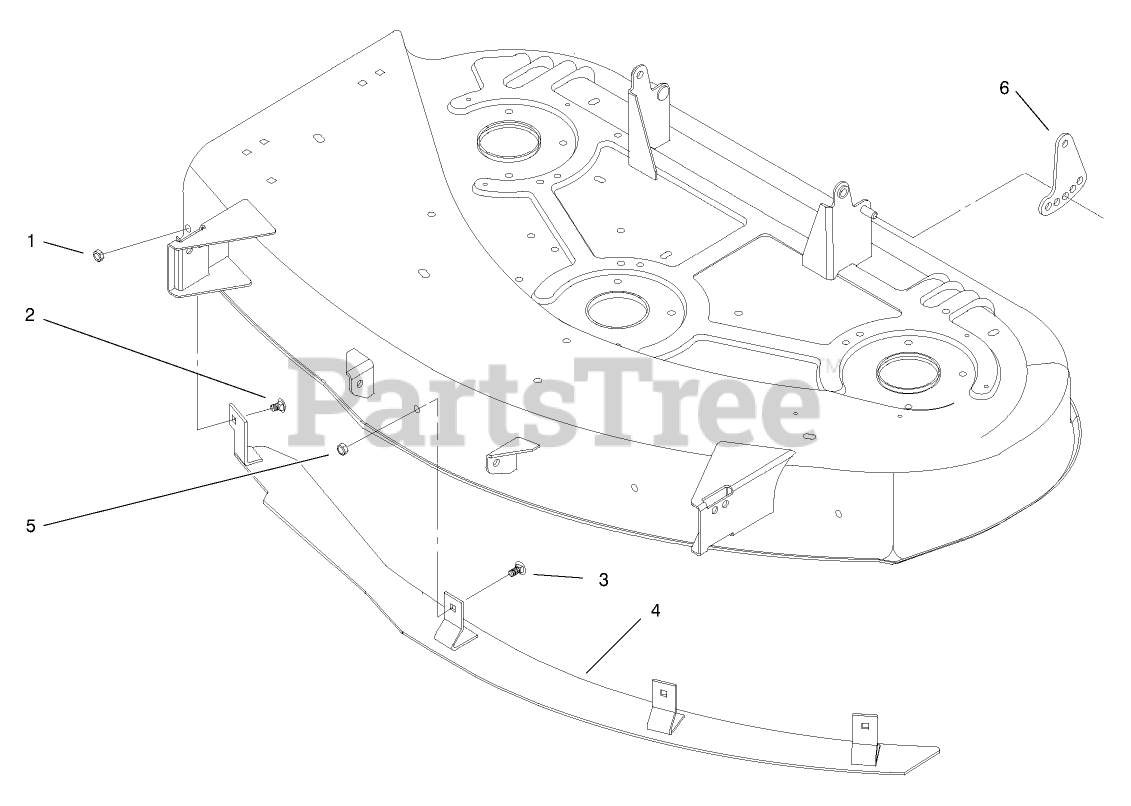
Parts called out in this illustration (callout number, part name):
1	NUT-LOCK, NI
2	BOLT-CARR
3	SCREW-CARR
5	NUT-LOCK, NI
6	LINK-ADJUSTING, HOC
